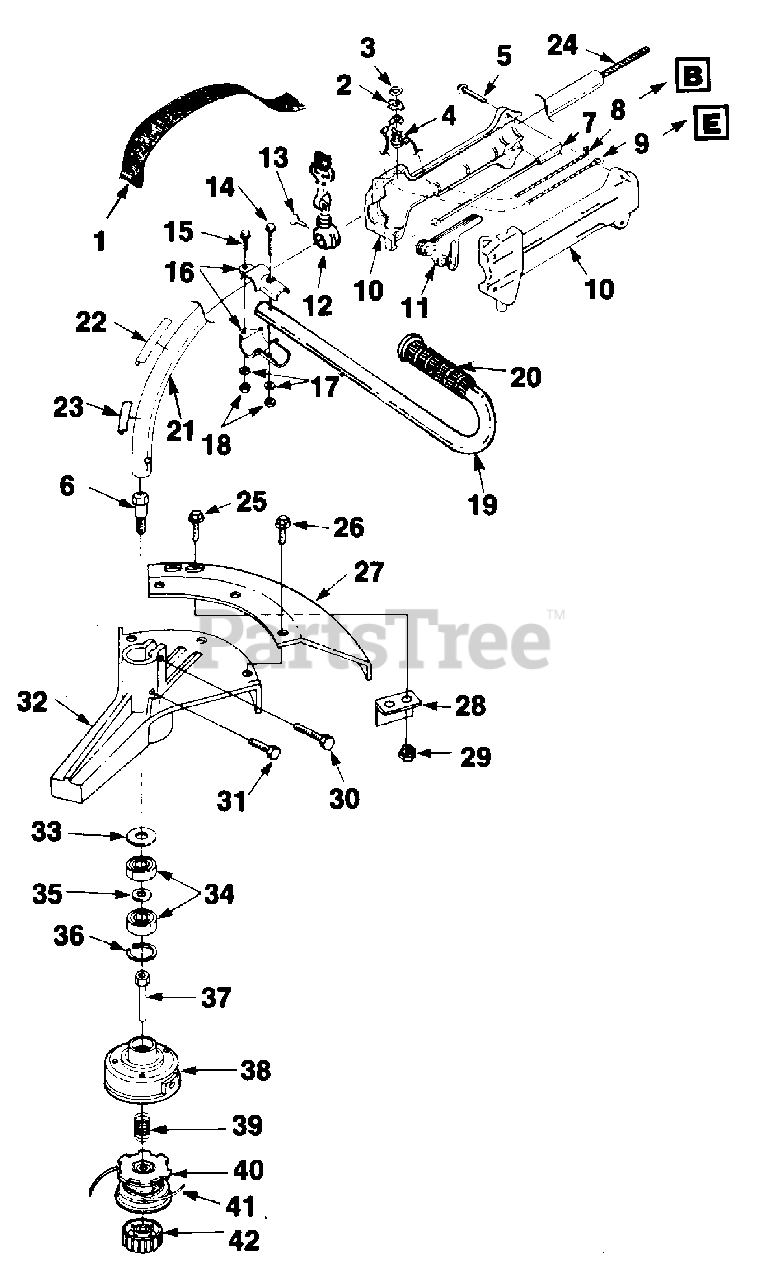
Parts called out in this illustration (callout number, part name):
2	PLATE- Indicating
3	NUT- Toggle switch
4	SWITCH- Toggle
5	SCREW- Plastite (#8 x 3/4")
6	SHAFT- Spindle
7	CABLE- Throttle
8	LEAD- Electrical
9	LEAD- Ground
10	HANDLE GRIP ASSEMBLY
11	TRIGGER
12	BRACKET- Hanger
13	SCREW- Thumb (10-24 x 1/2")
14	SCREW- (1/4-20 x 1 1/2")
15	SCREW- (1/4-20 x 7/8")
16	CLAMP- Handle bar
17	WASHER- (1/4")
18	NUT- (1/4-20)
19	"J" HANDLE BAR
21	HOUSING- Drive shaft
22	DECAL- Starting instr.
23	DECAL- Warning
24	SHAFT- Flexible
25	SCREW- (10-32 x 3/8")
26	SCREW- (1/4-20 x 1/2")
27	DEFLECTOR- Grass
28	BLADE- Cut off
29	NUT- (10-32)
30	SCREW- (1/4-20 x 1")
31	SCREW- (10-24 x 3/8")
32	HOUSING- Lower bearing
33	WASHER- Thrust
34	BEARING- Ball
35	SPACER- Bearing
36	RING- Snap
37	CONNECTOR- Drive
38	HOUSING & EYELET
39	SPRING- Compression
40	SPOOL & STRING
41	LINE REPLACEMENT (.095" Dia.) (1 lb.)
42	RETAINER- Spool (R.H. Thread)
